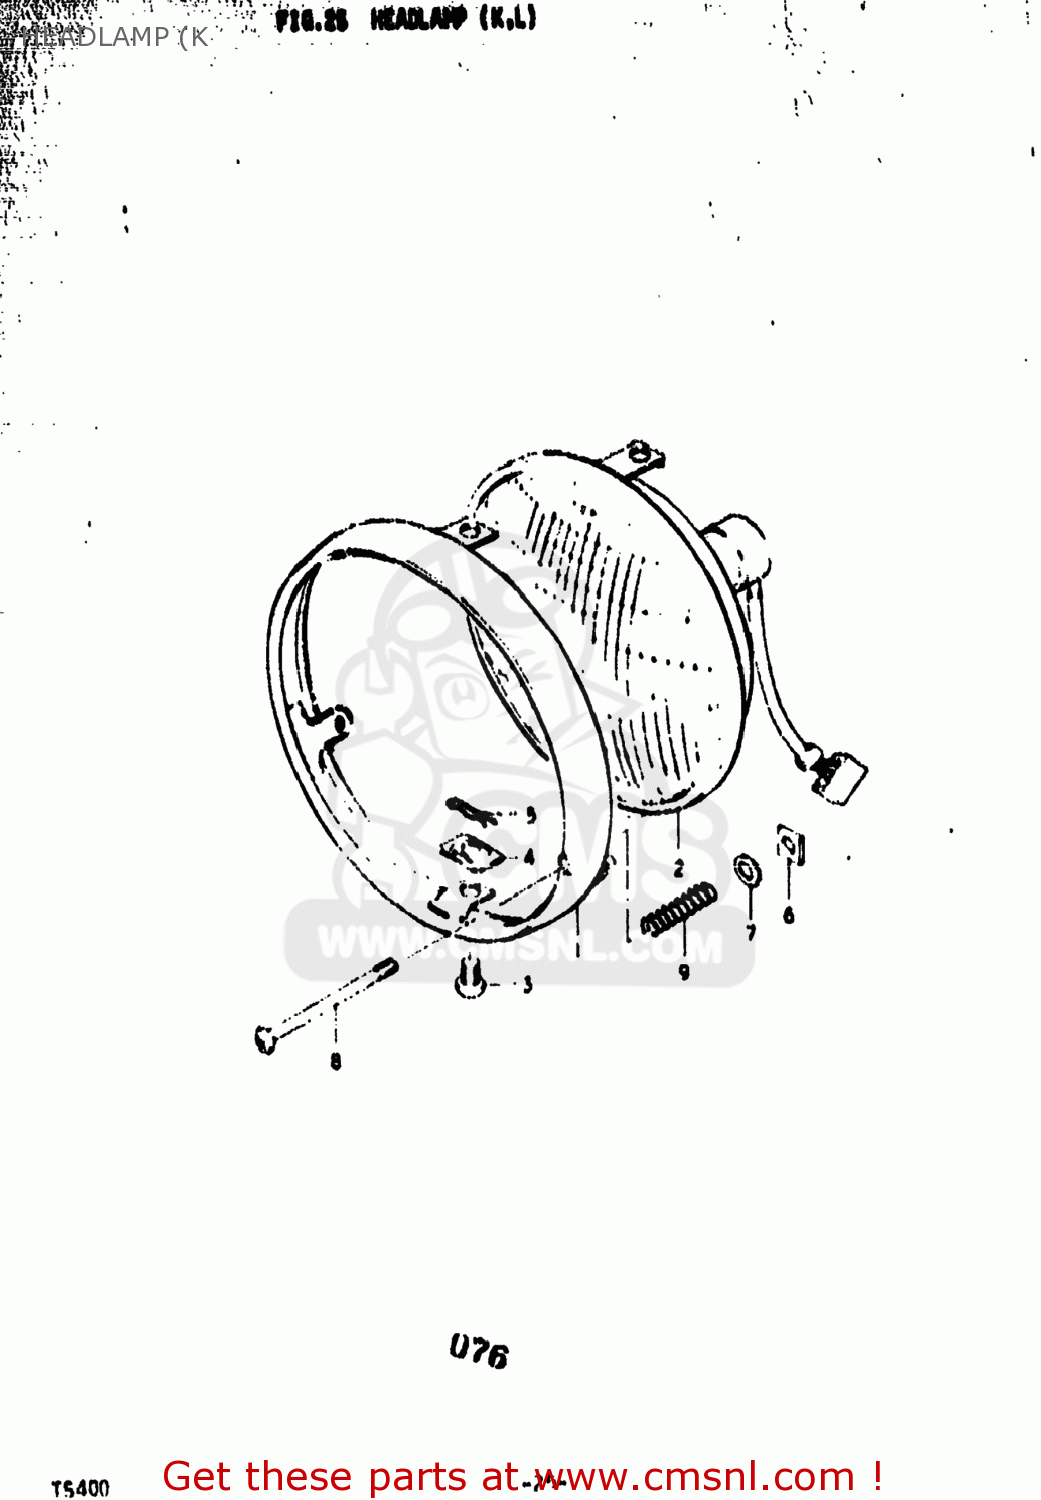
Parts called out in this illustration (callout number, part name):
1	RIM,HEADLAMP
2	LAMP UNIT
3	SCREW,LENS
4	NUT,ADJUSTING
5	CUSHION,HEADLAMP
6	NUT,HEADLAMP ADJUSTER
7	WASHER
8	SCREW,HEADLAMP ADJUST
9	SPRING,HEADLAMP ADJUST
